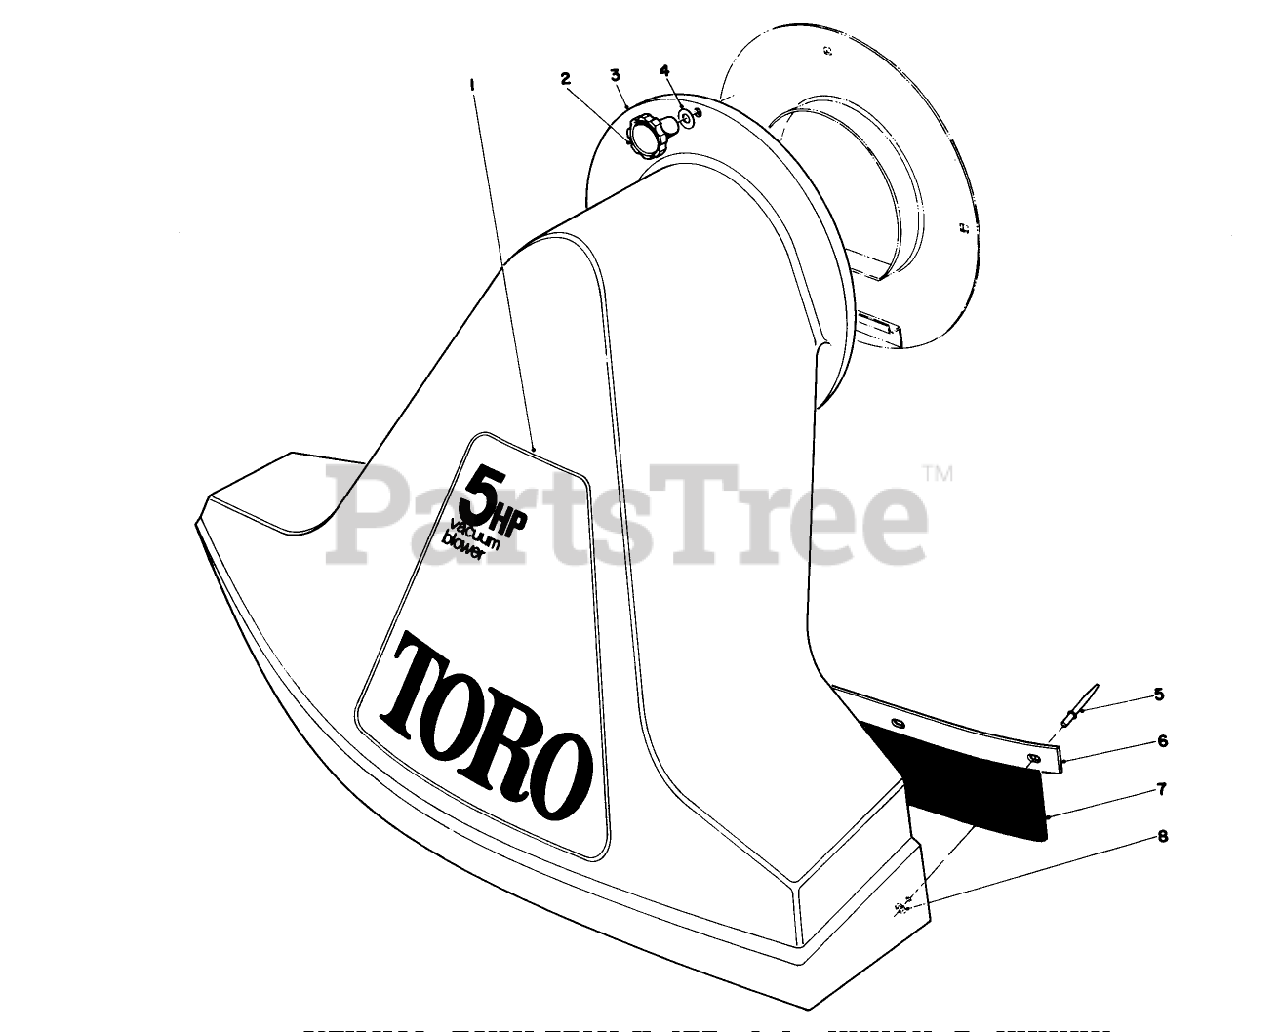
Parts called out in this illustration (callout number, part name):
3	SNOUT ASM
5	POP RIVET 3/16X.375LG
7	FLAP-RUBBER
8	WASHER-FLAT
